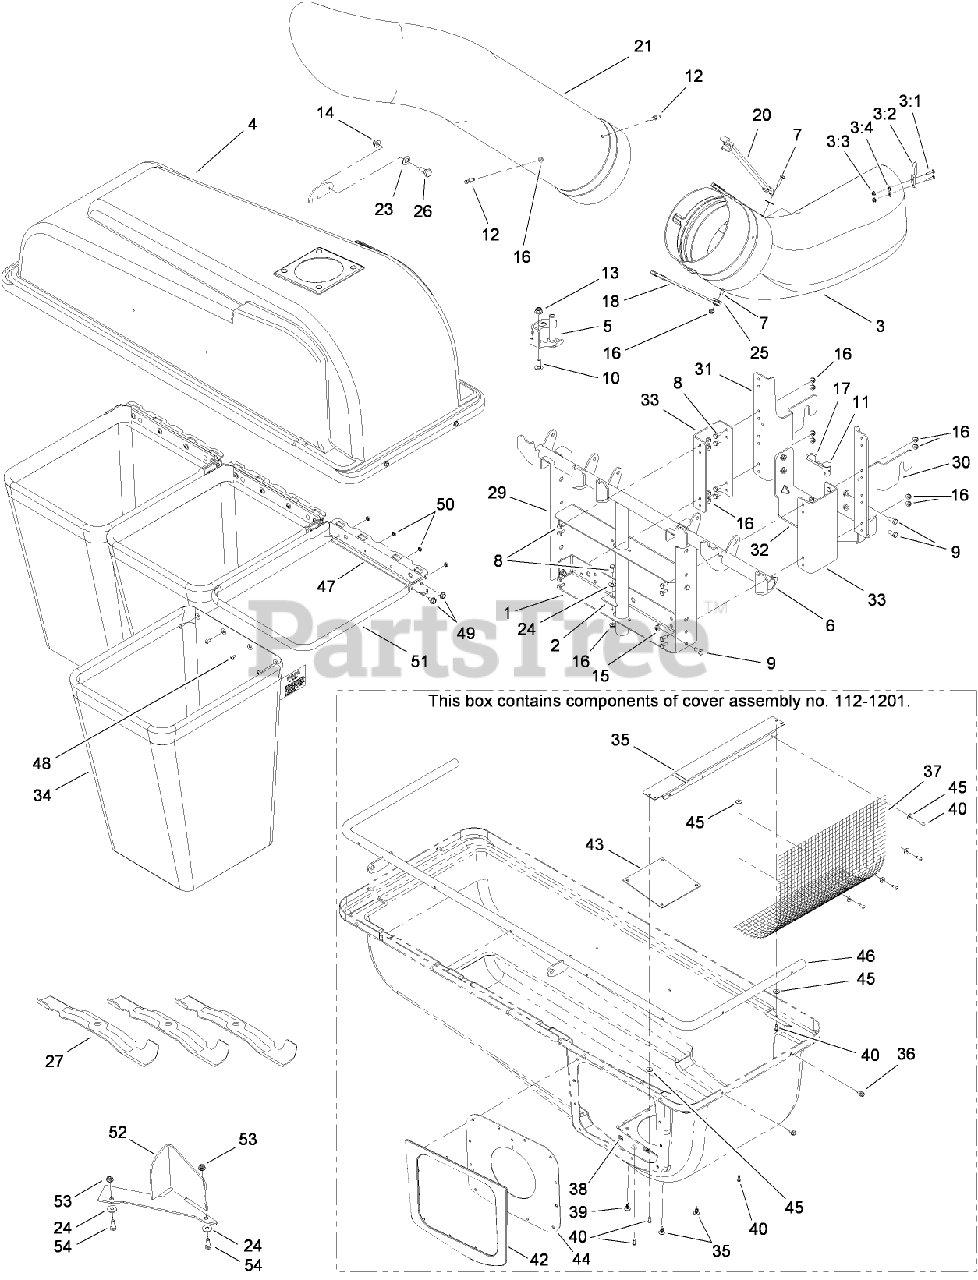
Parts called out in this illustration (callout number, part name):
1	BRACKET-SUPPORT, CATCHER
2	BRACKET-TUBING, ADAPTER
3	DISCHARGE CHUTE ASM
3:1	SCREW-HEX
3:2	ROD-MOUNT, BAG
3:3	NUT-LOCK, FLANGE
3:4	WASHER-FLAT
4	COVER ASM
5	CHUTE STOP BRACKET ASM
6	CATCHER SUPPORT ASM
7	SCREW-HH
8	SCREW-HH
9	SCREW-HH
10	BOLT-CARRIAGE
11	PIN-CLEVIS
12	PIN-CATCHER, GRASS
13	NUT-LOCK, HEX
14	NUT-LOCK, FLANGE
15	NUT-LOCK, FLANGE
16	NUT-LOCK, FLANGE
17	CLIP-HAIRPIN
18	STRAP-CHUTE
20	STRAP-CHUTE
21	TUBE-ELBOW, CATCHER
23	WASHER-BELL
24	WASHER-SPRING
25	WASHER-FLAT
26	BOLT-SHOULDER
27	BLADE-BAGGING (STAR, 17.90 INCH)
29	BRACKET-SUPPORT
30	BRACKET-CATCHER, RH
31	BRACKET-CATCHER, LH
32	BRACKET-CROSS, SUPPORT
33	BRACKET-CATCHER
34	BAG-GRASS
35	BRACKET-MOUNTING, SCREEN
36	SCREW-HWH
37	SCREEN
38	NUT-PUSH
39	CLIP-RATCHET
40	RIVET-POP
42	SEAL-RETAINER
43	PLATE-PLASTIC
44	SEAL-BAG, GRASS
45	WASHER-FLAT
46	BRACKET-HINGE
47	BRACKET-HANGER, BAG
48	SCREW-TRUSS, MACHINE
49	SCREW-HWH
50	NUT-SEMS
51	FRAME-BAG, CATCHER
52	Baffle-Deck
53	NUT-LOCK, FLANGE
54	SCREW-HH
